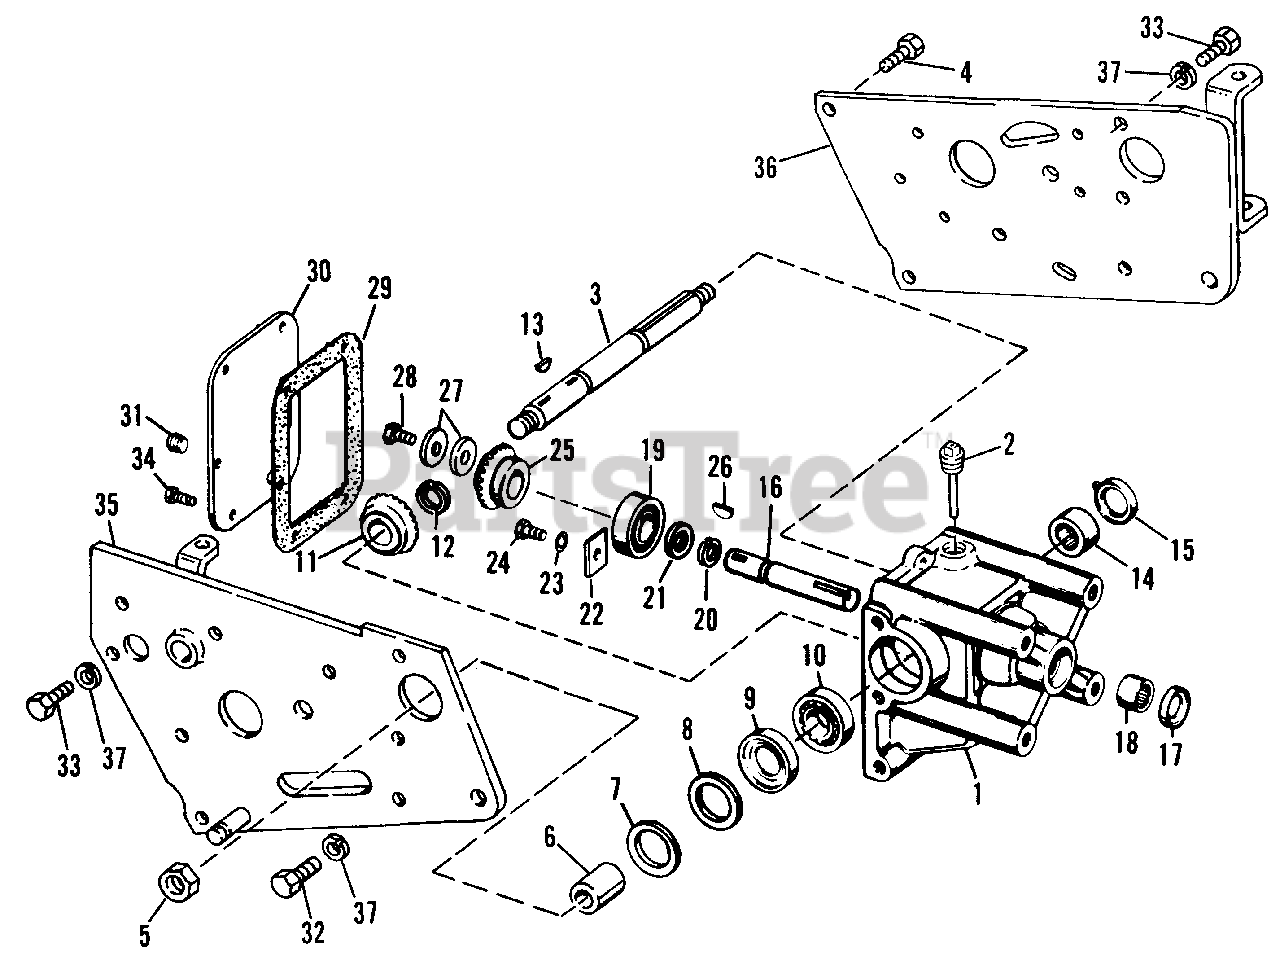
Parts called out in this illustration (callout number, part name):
1	Bevel Gear Housing, w/Bearings
2	Plug Assy., Oil Fill
3	Driven Shaft
4	Hex Capscrew, 7/16"-14 x 1-1/4"
5	Hex Jam Nut
7	Shim (As Required)
10	Ball Bearing
11	Bevel Driven Gear
12	Retaining Ring
14	Needle Bearing
16	Drive Shaft
18	Needle Bearing
19	Ball Bearing
20	Retaining Ring
22	Bearing Clamp Plate
23	Lockwasher, 5/16"
24	Hex Capscrew, 5/16"-18 x 5/8"
25	Bevel Driven Gear
27	Washer, Compression
28	Hex Capscrew, 5/16"-18 x 3/4"
30	Housing Cover Assembly
31	Pipe Plug
32	Hex Capscrew, 7/16"-14 x 1"
33	Hex Capscrew, 7/16"-14 x 1-1/4"
34	Hex Capscrew, 1/4"-20 x 5/8"
35	Right Hand Side Plate Assy.
36	Left Hand Side Plate Assy.
37	Lockwasher, 7/16"
